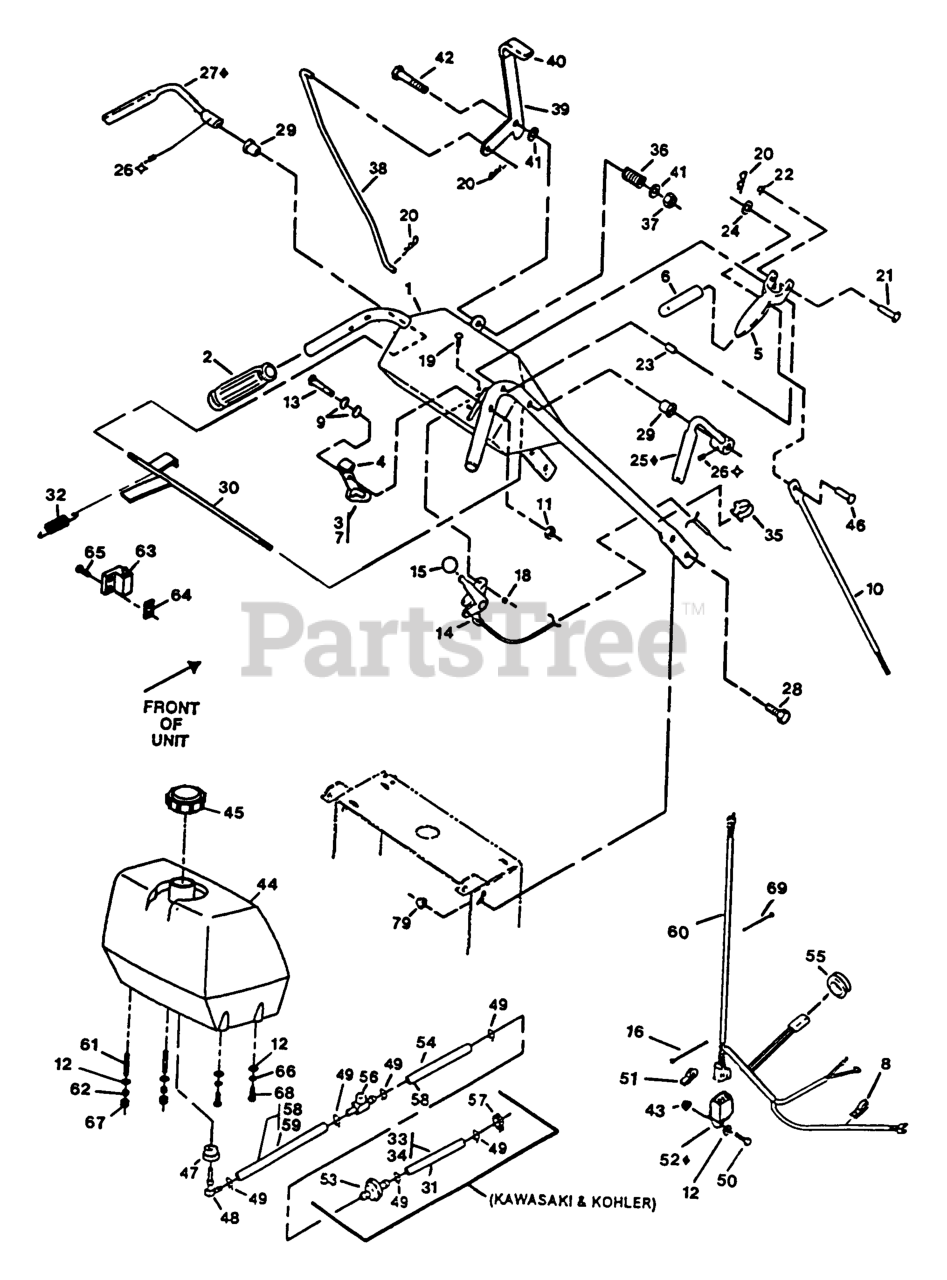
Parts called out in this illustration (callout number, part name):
3	LATCH,W/GRIP LH
4	GRIP-LATCH
5	DRIVE LEVER ASM
6	GRIP-LEVER, DRIVE
7	LATCH,W/GRIP RH
8	CLIP-LOOM
9	WASHER-SPRING
10	LINKAGE-WHEEL, DRIVE
14	CABLE-CONTROL, THROTTLE
15	KNOB-BALL
16	TIE-CABLE
19	BOLT-CARR
20	PIN-COTTER
21	PIN-LEVER, DRIVE
22	NUT-PUSH
23	PIN-ROLL
26	SCREW-SET
29	BUSHING-NYLON
30	WLD,ROD OPC
31	LINE-FUEL
32	SPRING-EXTENSION
33	HOSE-FUEL
34	HOSE-LINE, FUEL
35	CLIP-CABLE
36	SPRING-COMPRESSION
38	LINKAGE-BLADE, UPPER
40	GRIP-LEVER
45	CAP-FUEL
46	PIN,CLEVIS
48	ELBOW-TANK, FUEL
51	CLIP-LOOM
52	MODULE-INTERLOCK
54	HOSE-LINE, FUEL
55	GROMMET
56	VALVE-FUEL
57	CLAMP-HOSE
58	HOSE-FUEL
59	HOSE-FUEL
62	SPRING-TANK, FUEL
63	SWITCH-OPEN, NORMALLY
64	PLATE-TAPPED
66	WASHER-LOCK
69	TIE-PLASTIC
